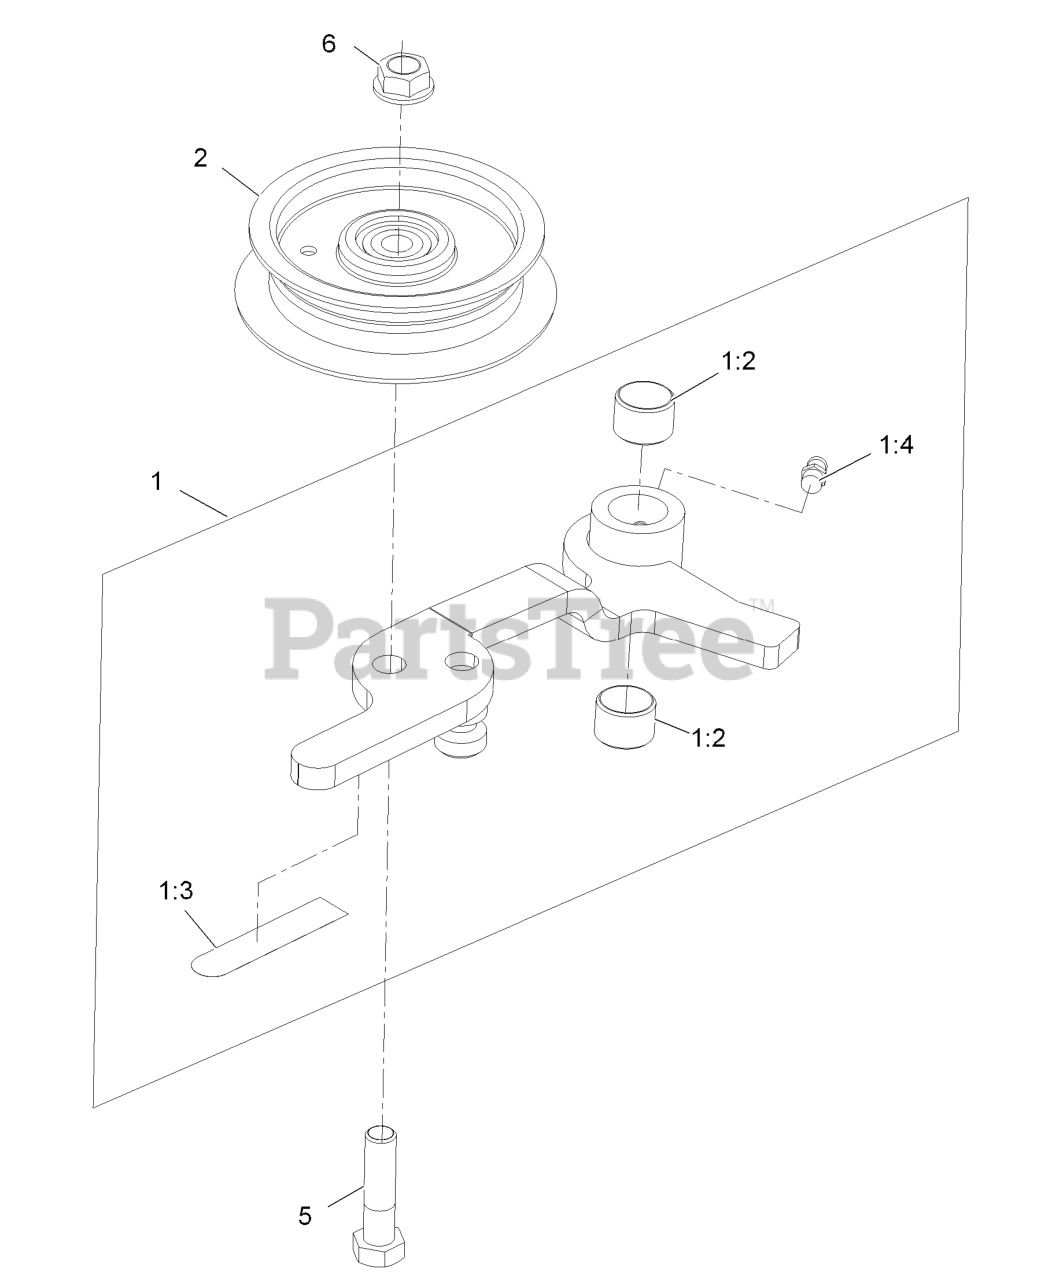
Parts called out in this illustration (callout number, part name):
1	ASM, IDLER ARM - SERVICE
1:2	BUSHING
1:3	DECAL-WARNING
1:4	FITTING-GREASE
2	IDLER-FLAT
5	SCREW-HH
6	NUT-HHF, WHIZ
